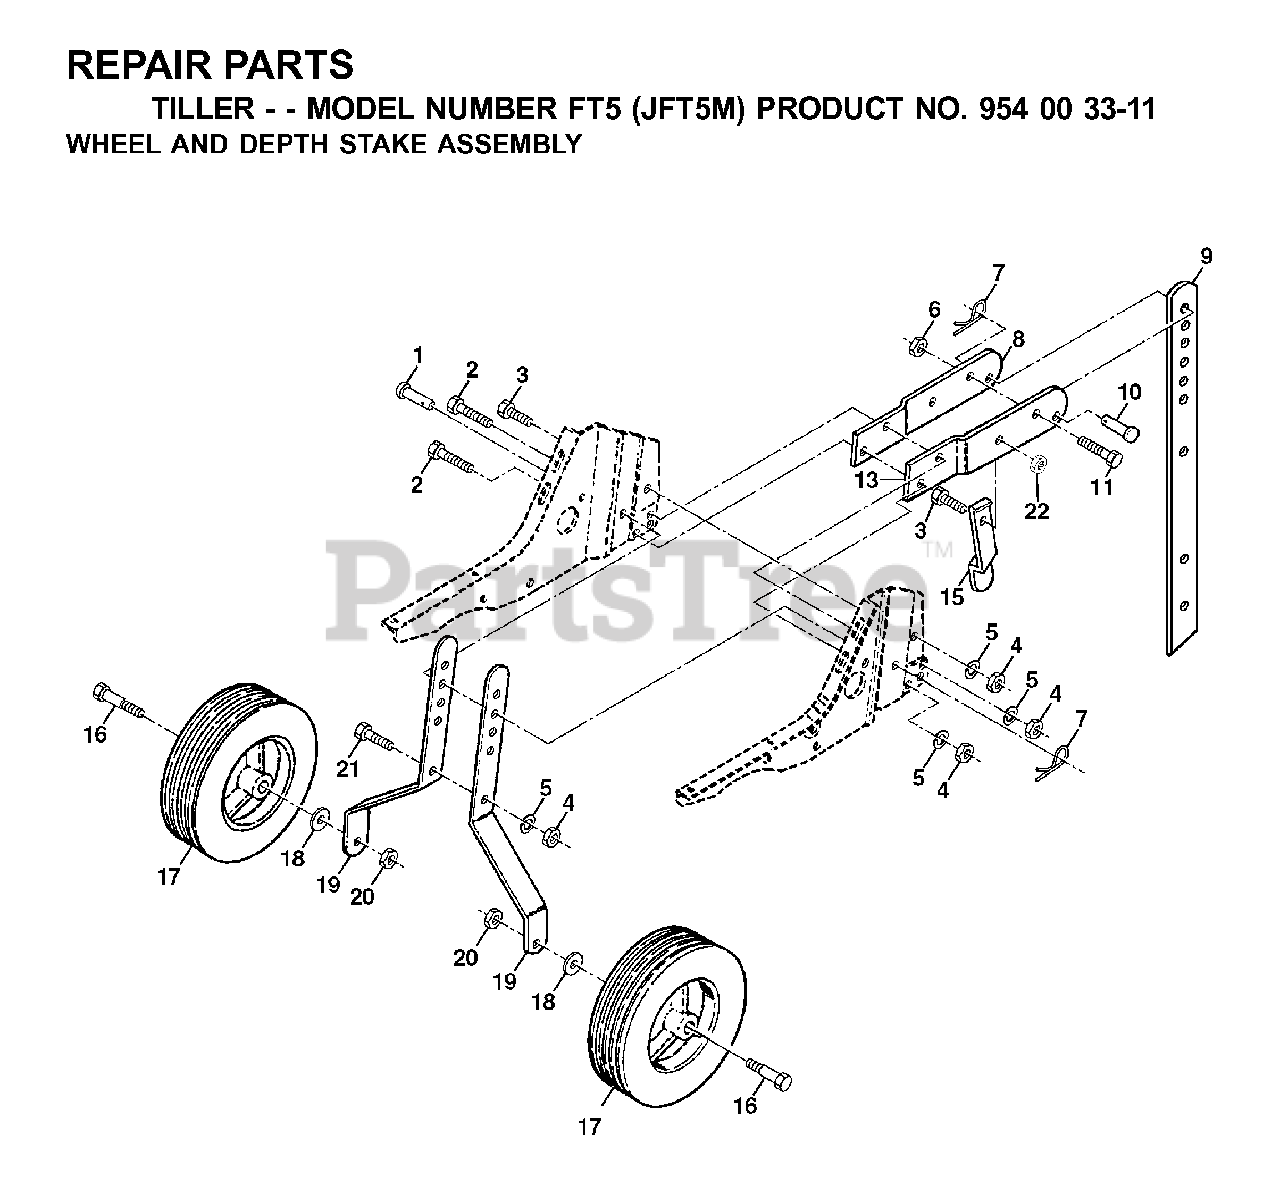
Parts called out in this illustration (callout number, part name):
1	PIN
2	BOLT
3	BOLT
5	LOCKWASHER
6	NUT
7	SPRING.RETAINER
8	SUPPORT.STAKE.RH.BLACK
9	RP STAKE.DEPTH.13.25.W/9HOLES
11	BOLT
16	BOLT.SHOULDER
18	WASHER
20	LOCKNUT
21	BOLT RB
22	NUT.71038.31-18.HEX.NYLOCK
